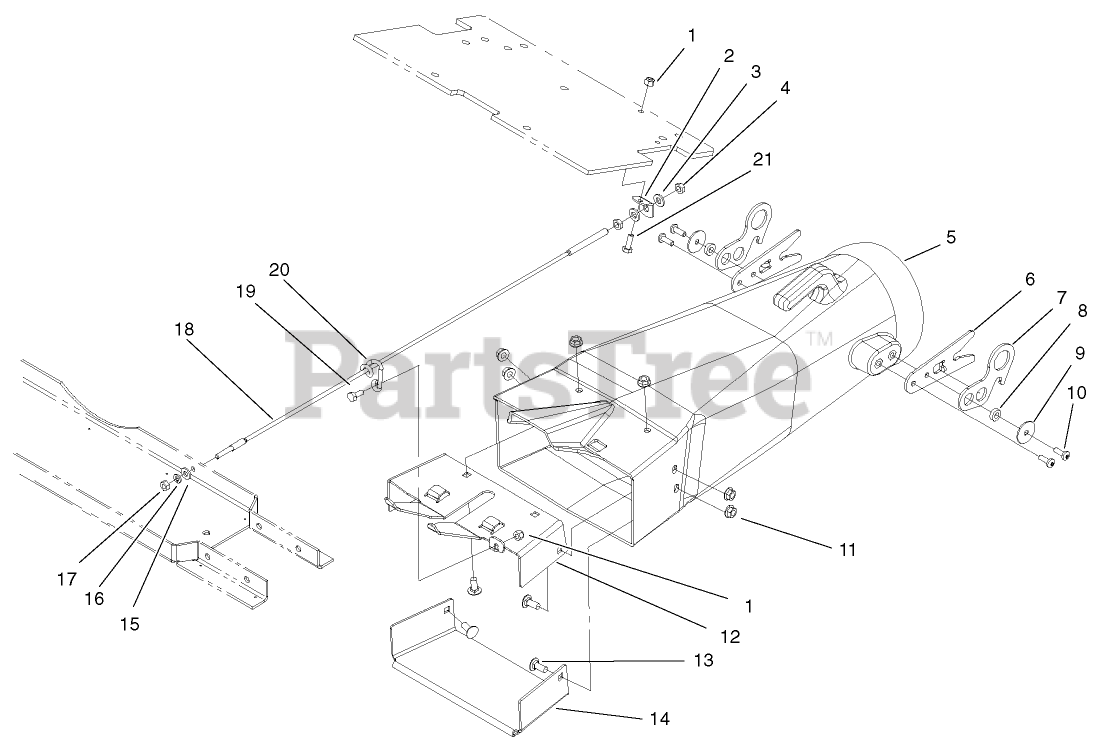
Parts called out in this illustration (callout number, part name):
1	NUT-LOCK, NI
2	BRACKET-SPRING
3	WASHER-PLAIN
4	NUT-JAM
5	Plenum
6	PLATE-GUIDE
7	PLATE-LATCH
8	SPACER
9	WASHER-FLAT
10	SCREW-TORX
11	NUT-HF
12	PLATE-PLENUM, TOP
13	SCREW-CARR
14	PLATE-PLENUM, BOTTOM
15	WASHER-FLAT
16	WASHER-LOCK
17	NUT-HEX
18	CABLE-TENSION
19	SCREW-HH
20	GUIDE-CABLE
21	SCREW-HH
